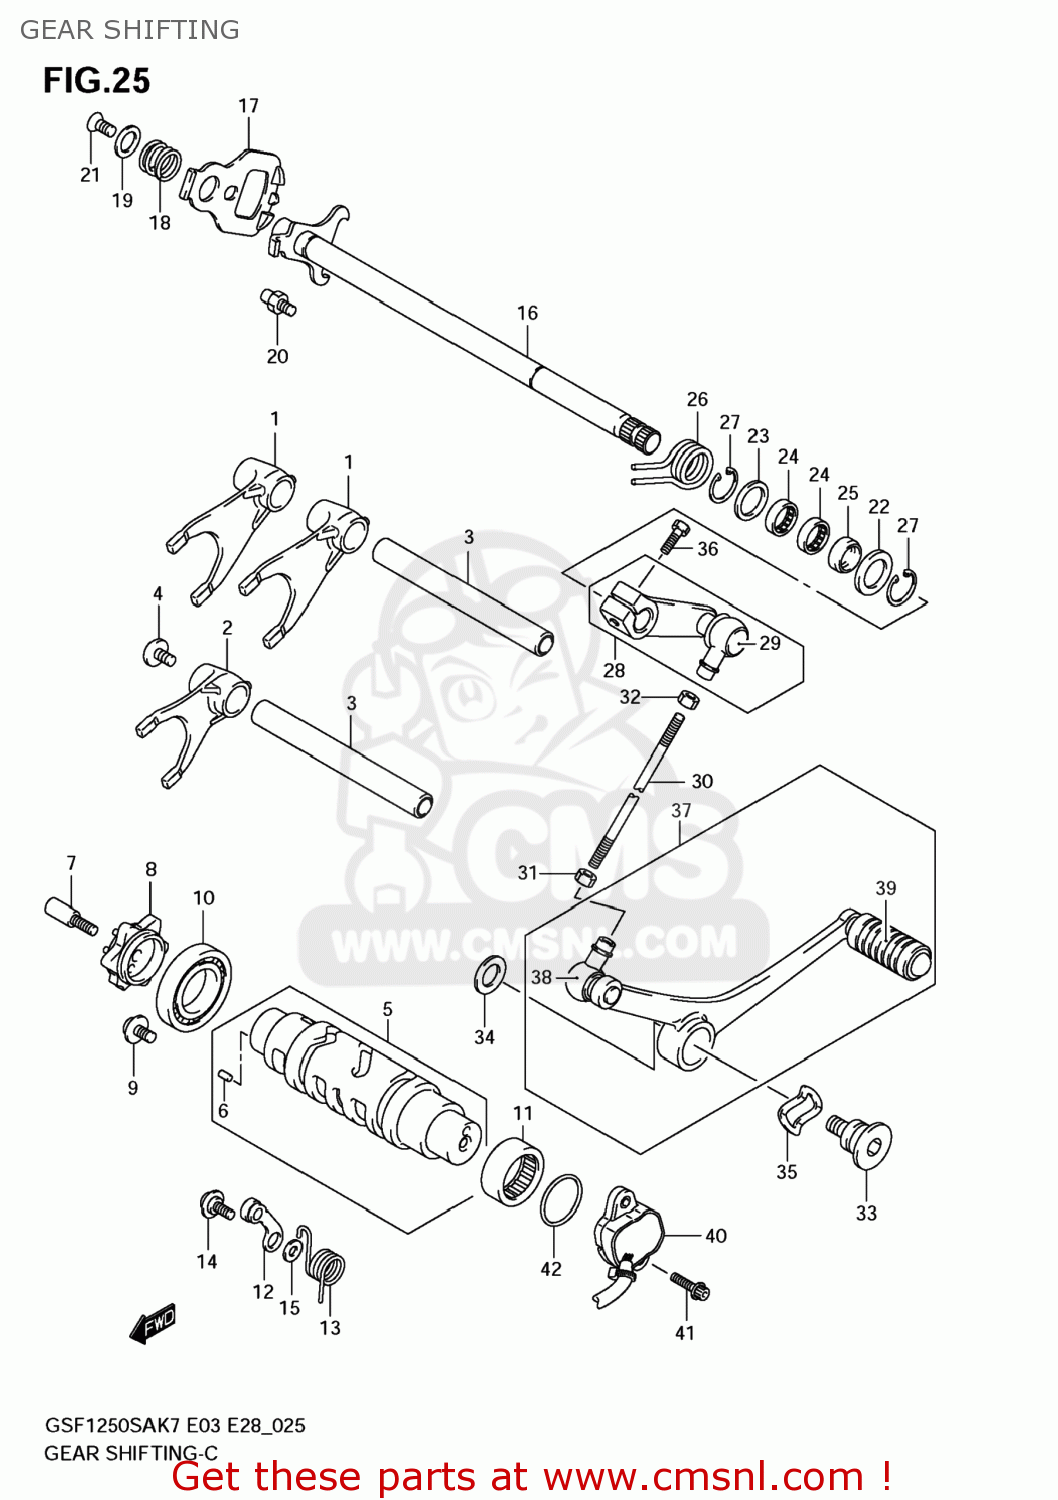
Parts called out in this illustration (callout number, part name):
1	FORK,GEAR SHIF
2	FORK,GEAR SHIF
3	SHAFT,GEAR SHIFT FORK(L:128)
4	SCREW(6X12)
5	CAM,GEAR SHIFT
6	PIN
7	BOLT,GEAR SHIFT CAM PLATE
8	PLATE,GEAR SHIFT CAM
9	SCREW(6X12)
10	BEARING(25X47X8)
11	BEARING(25X32X12)
12	STOPPER,SHIFT CAM
13	SPRING,GEAR SHIFT CAM STOPPER
14	BOLT(6X14.3)
15	WASHER
16	SHAFT,GEAR SHIFT
17	PLATE,GEAR SHIFT CAM DRIVE
18	SPRING,GEAR SHIFT PLATE RETURN
19	WASHER,GEAR SHIFT SHAFT END
20	STOPPER,GEAR SHIFT ARM
21	SCREW(6X16)
22	WASHER(14X29X0.8)
23	SHIM(14X24X1)
24	BEARING(14X20X12)
25	SEAL,OIL(14X22X6)
26	SPRING
27	CIRCLIP
28	ARM,GEAR SHIFT LINK
29	COVER,DUST
30	ROD,GEAR SHIFT LINK
31	NUT
32	NUT
33	BOLT,GEAR SHIFT LEVER
34	WASHER(10.5X28X2.3)
35	WASHER
36	BOLT
37	LEVER ASSY,GEAR SHIFT
38	COVER,DUST
39	RUBBER,GEAR SHIFT PEDAL
40	SENSOR ASSY,GE
41	BOLT(5X16)
42	O RING(D:2.4,ID:26.2)
